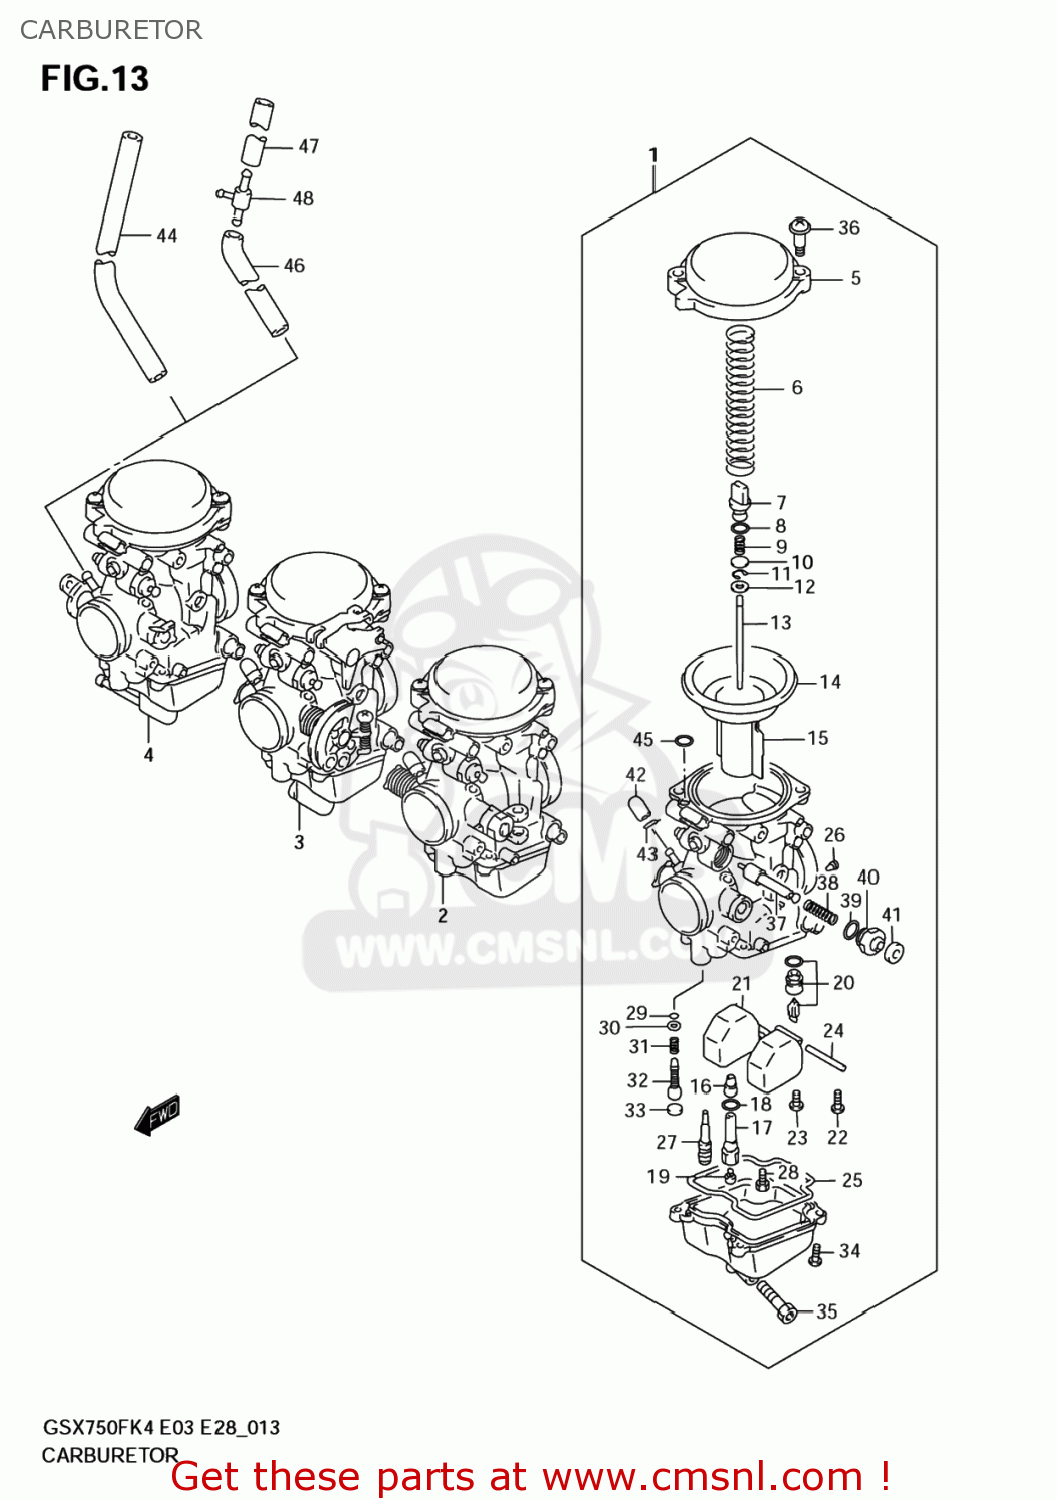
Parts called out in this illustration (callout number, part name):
1	CARBURETOR ASSY,L
2	CARBURETOR ASSY,ML
3	CARBURETOR ASSY,MR
4	CARBURETOR ASSY,R
5	COVER,DIAPHRAGM
6	SPRING
7	HOLDER
8	O RING(D:1.9,ID:4.8)
9	SPRING
10	WASHER
11	E RING,MULTIPLE JET NOZZLE
12	RING
13	NEEDLE,JET
14	DIAPHRAGM
15	VALVE,PISTON
16	JET,NEEDLE(P-0M)
17	HOLDER,JET
18	O RING
19	JET,MAIN
20	VALVE ASSY,NEEDLE
21	FLOAT ASSY
22	SCREW
23	SCREW
24	PIN,FLOAT
25	GASKET (NAS)
26	JET,POWER(130)
27	JET,PILOT(12.5)
28	JET,STARTER(50)
29	O RING,PILOT AIR SCREW
30	WASHER
31	SPRING,THROTTLE SCREW
32	ADJUSTER
33	PLUG
34	SCREW
35	SCREW,DRAIN
36	SCREW
37	PLUNGER
38	SPRING
39	O RING
40	GUIDE SCREW,PLUNGER
41	CAP,STARTER VALVE
42	CAP
43	CLIP
44	HOSE(5X10X600)
45	O RING
46	HOSE(5X9X600)
47	HOSE(5X9X600)
48	NIPPLE
